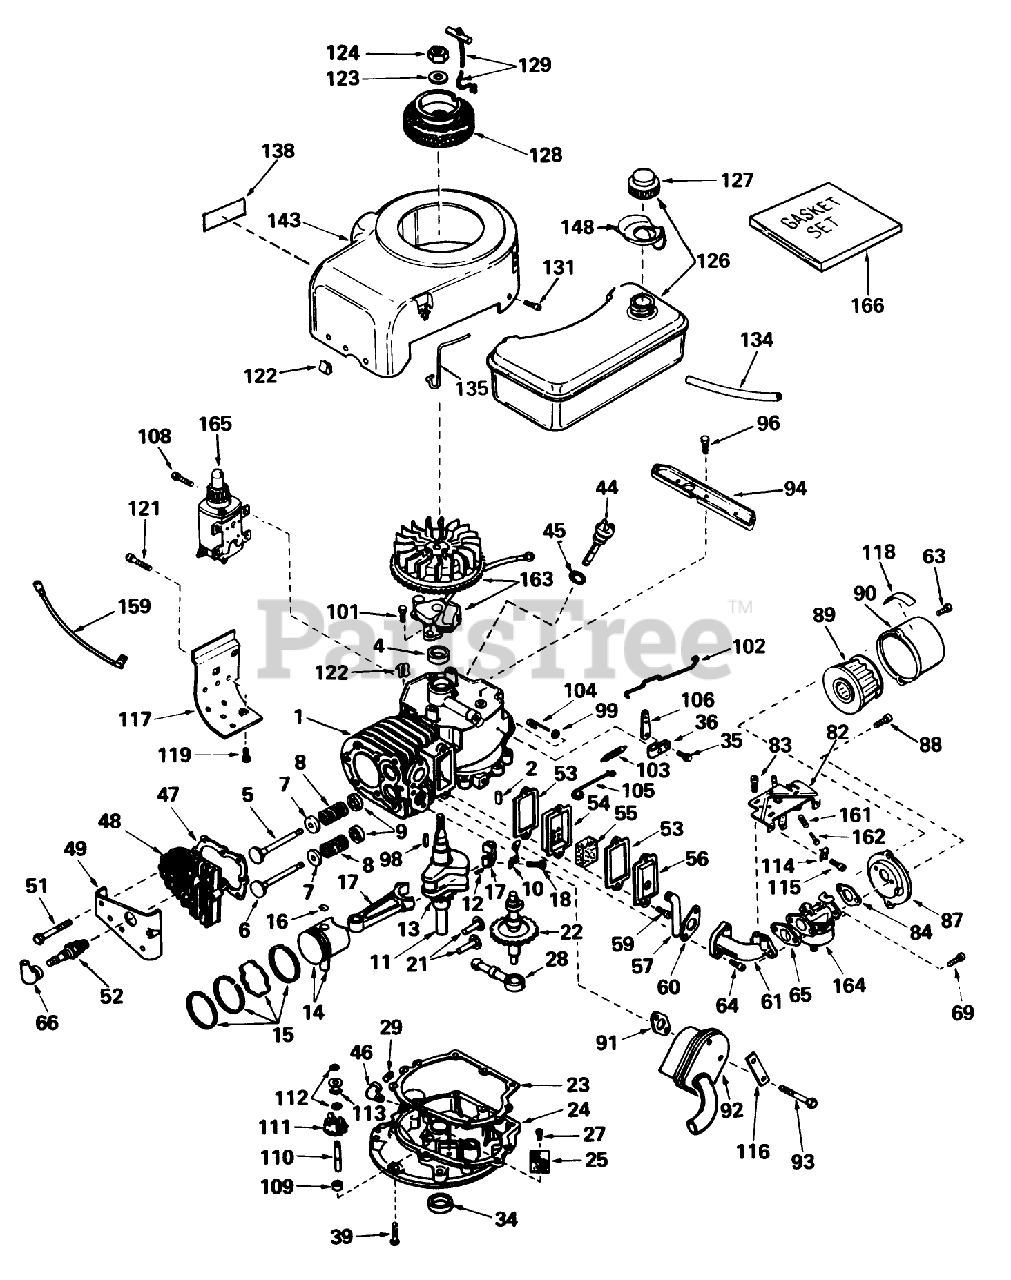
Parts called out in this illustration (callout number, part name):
1	Cylinder Assy. (Incl. Nos. 2, 4 44)
2	Pin-Dowel
4	Oil Seal
5	Valve, Intake (Standard)(Incl. No. 9)
5	Valve, Intake (1/32" oversize)(Incl. No. 9)
6	Valve, Exhaust (Standard)(Incl. No. 9)
6	Valve, Exhaust (1/32" oversize)(Incl. No. 9)
7	Cap-Spring, Valve
8	Spring-Valve
9	Keeper-Spring, Valve
10	Plate, Lock
11	Crankshaft Assy. (Incl. Nos. 12 13)(Model 935 only)
12	Pin, Groove
13	Gear-Crankshaft
14	Piston Pin Assy. (Incl. 2 of No. 16)(Standard)
14	Piston Pin Assy. (Incl. 2 of No. 16)(.010 oversize)
14	Piston Pin Assy. (Incl. 2 of No. 16)(.020 oversize)
15	ORing
15	Ring Set (.010" OS)
15	Ring Set (.020" OS)
17	Rod Assy., Connecting (Incl. Nos. 10 18)
18	Screw, Hex Hd.
21	Lifter-Valve
22	Screw
23	Gasket-Cover, Cylinder
24	Flange Assy., Mounting (Incl. Nos. 25, 27, 29, 34, 45 110)
25	Screen-Oil Filter
27	Screw
28	Pump, Oil
29	Plug-Drain, Oil (SQH 1/4-18)
34	Seal-Oil
35	Screw
36	Clamp-Lever, Governor
39	Screw (1/4-20 x 1-1/4)
44	Dipstick, Oil (Incl. No. 45)
45	Gasket
46	Elbow, 90
47	Gasket-Cylinder Head
48	CYLINDER HEAD
49	Cover-Head, Cylinder
51	Screw Hex Hd. Cap
52	Plug, Spark (Champion RCJ-8)
53	Gasket-Breather
54	Body-Breather
55	Element-Breather
56	Cover-Valve
57	Tube-Breather
59	Screw
60	Gasket-Intake
61	Pipe-Intake
63	Screw
64	Screw (T-30, 5/16-18x1-3/32)
65	Gasket
66	Cover-Spark Plug
69	Screw-Hex Hd.
82	Control Assy., Speed (Incl. Nos. 161 162)
83	Screw (10-24 x 9/16)
84	Gasket
87	Bracket
88	Screw (10-32 x 1/2)
89	Element
90	Body
91	Gasket Exhaust
92	Muffler
93	Screw Hex Hd.
94	Bracket-Blower Housing
96	Screw (1/4-20x19/32)
98	Key-Flywheel
99	Washer-Flat
101	Screw
102	Link Governor
103	Spring Governor
104	Rod, Governor (Incl. Nos. 146)
105	Link Governor Spring
106	Lever-Governor
108	Screw
109	Spacer
110	Shaft, Governor
111	Governor Gear ASM
112	Ring-Retaining
113	Spool-Governor
114	Conduit
115	Screw (10-32 x 3/8)
116	62513 SNWTHWR W/284
117	Emnsion, Blower Housing
118	Decal
119	Screw
121	Screw
122	51004 GIL ROTARY TI
123	Washer
126	Tank Assy., Fuel (Incl. No. 127)
127	Cap, Fuel
128	Hub Screen, Rope Starter
129	Rope Assy., Starter
131	Screw, Hex Hd.
134	Line-Fuel (8.62)
135	Clamp, Tank Holdown
138	480B GIL SNWTHWR O/
143	Housing Blower
148	Deflector-Fuel
159	SPOOL RETAINER (10-PK)
161	Spring-Compression
162	Screw
163	Magneto
164	Carburetor
165	Tine Shaft
166	Gasket Set
